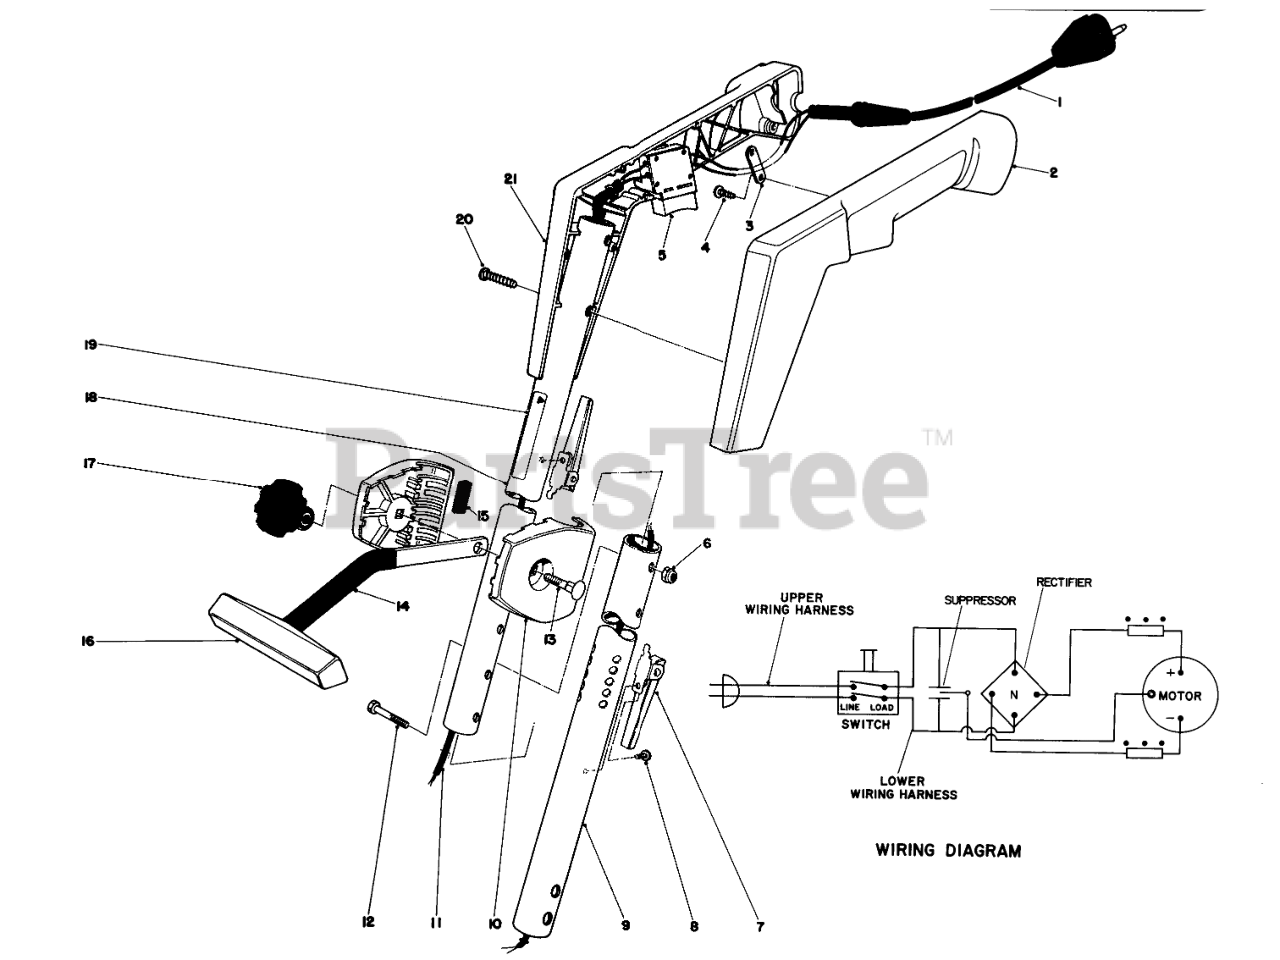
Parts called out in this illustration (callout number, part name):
1	Power Cord
2	Left Hand Grip
3	Clamp
4	SCREW-PPH
5	Switch
6	NUT-LOCK, NI
7	Clamp, Storage
8	Screw-Phcr
9	Lower Tubing
10	T-HANDLE BRKT(RED)
11	Wiring Harness
12	Screw
13	BOLT-CARR
14	Sleeve
15	RUBBER INSERT
16	Tee Handle
18	Upper Tubing
19	Caution Decal
20	16 Self Tapping Screw
21	Right Hand Grip
